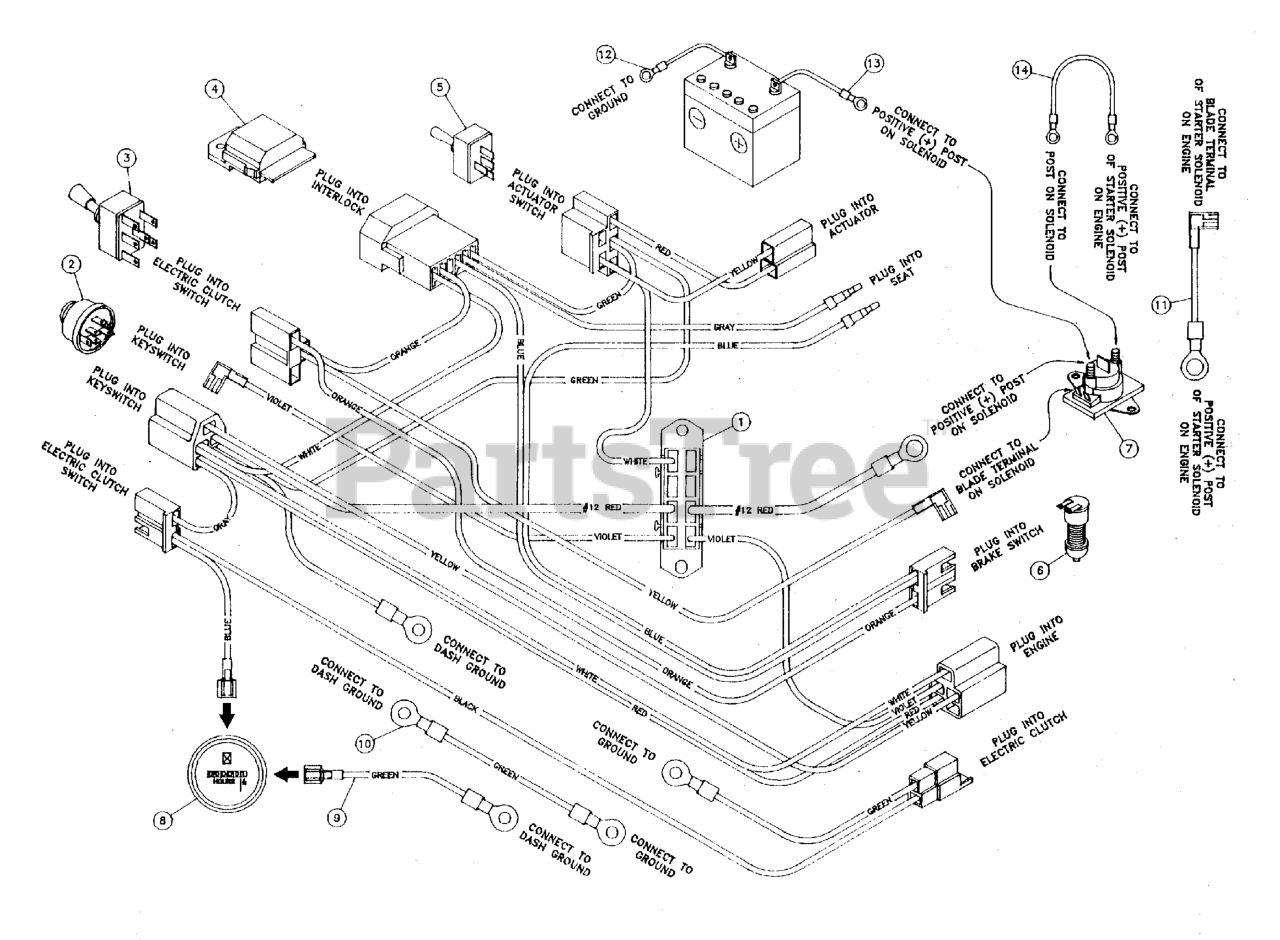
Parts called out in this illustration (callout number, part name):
1	RIDER WIRE HARNESS
2	SWITCH, IGNITION, 6 POST
3	SWITCH, Electric Clutch
4	INTERLOCK RELAY HARNESS
5	SWITCH, Actuator
6	SWITCH, Plunger, NO
7	SOLENOID, Starter
8	HOUR METER
9	HOUR METER GROUND WIRE
10	DASH GROUND WIRE
11	STARTER JUMPER WIRE
12	BATTERY CABLE, NEG, 22, 1/4-5/16
13	POSITIVE (+) BATTERY CABLE, 30"
14	CABLE, Starter
